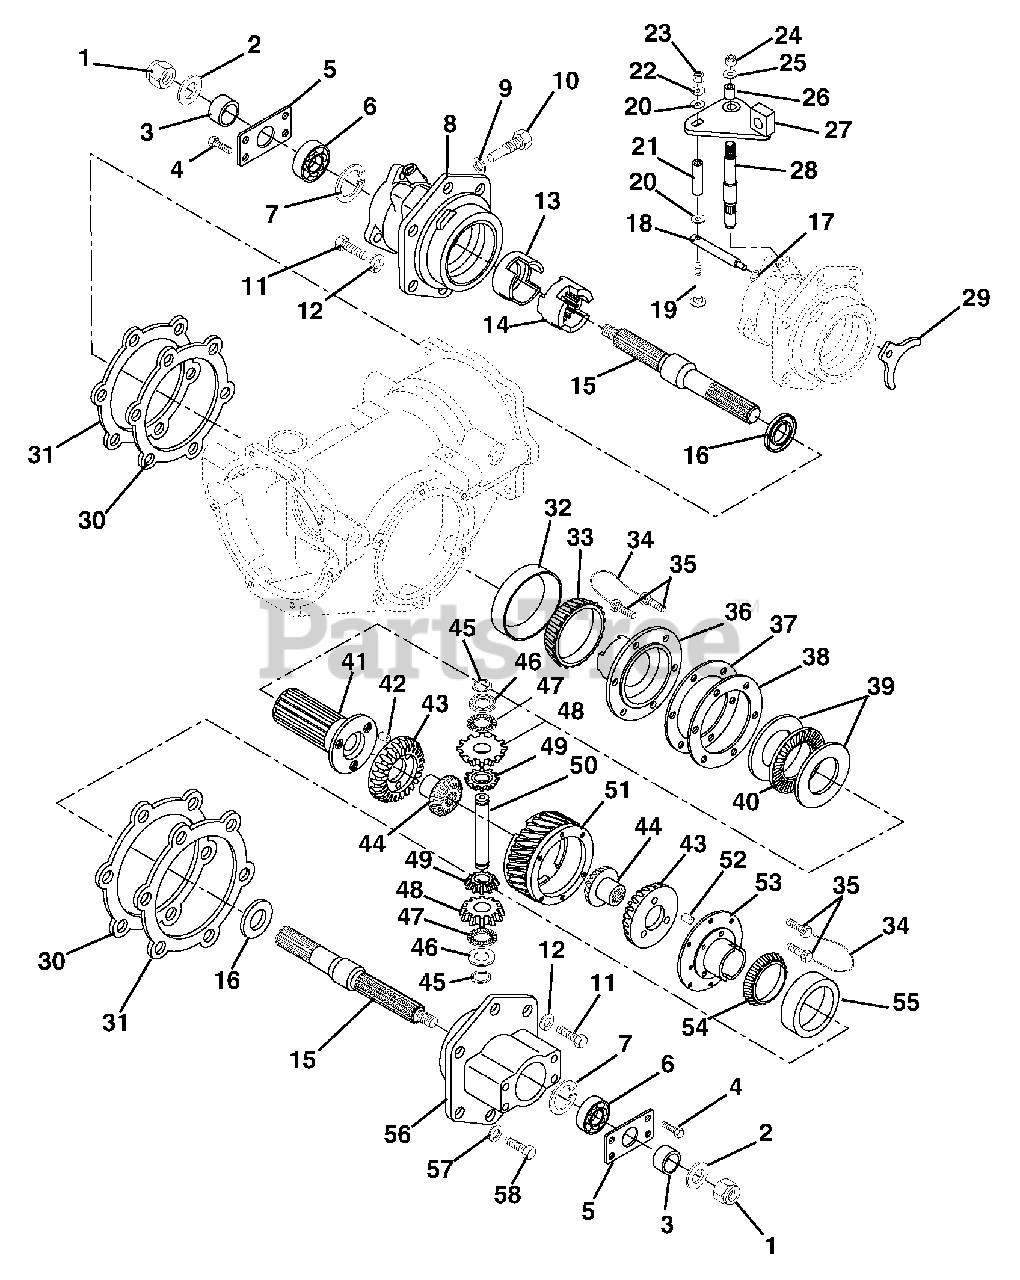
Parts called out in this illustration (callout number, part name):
1	Nut-Locking-Jam-Nylon .75-10
2	Washer-Flat .812 x 1.50 x .135
3	Spacer 1.008 x 1.377 x .509
4	Bolt-Hex .38-16 x .75 Grade 5
5	Plate, End
6	Bearing-Ball 1.0 x 2.0 x .56
7	Ring-Retaining-Internal 2.210 x .062
8	Housing, Axle, 2 Speed
9	Washer-Nut .63 x .875 x .062
10	Bolt-Hex .62-18 x .493 x 1.25
11	Bolt-Hex .50-13 x 1 Grade 5
12	Washer-Lock .50 x .125
13	Clutch, Stationary
14	Clutch, Shifting
15	Axle, Straight
16	Seal 1.1988 x 2.00 x .250
17	O-Ring .437 x .625 x .093
18	Pin-Clutch Sliding
19	Bolt-Round Head Square Neck .25-20 x 2.25 Grade 8
20	Washer-Flat-Steel .406 x .812 x .065
21	Bushing-Sleeve .277 x .375 x 1.37
22	Washer-Flat-Steel .281 x .625 x .065
23	Nut-Locking-Center .250-20 Grade 2
24	Nut-Locking-Center .312-18 Grade 2
25	Washer-Flat-Steel .344 x .688 x .065
26	Bushing-Sleeve .377 x .503 x .88
27	Weldment, Arm Shifter
28	Pivot, Stationary
29	Yoke, Shifting
30	Gasket, Axle Housing
31	Assembly, Advance Casting
32	Bearing-Race 4.34 x .741
33	Bearing-Cone 2.69 x .87
34	Wire, Bolt
35	Bolt-Special .31-18 x .75
36	Housing, Clutch
37	Shim, .020 Clutch Worm Gear
38	Shim, .005 Clutch Worm Gear
39	Washer-Thrust 2.002 x 2.740 x .031
40	Bearing-Needle-Thrust 2.0 x 2.74 x .010
41	Shifter, Splined Pinned
42	Pin-Dowel .375 x .375
43	Gear, Pinned Bevel
44	Gear, Differential Bevel
45	Ring-Retaining .697 x .93
46	Bushing, Flange .761 x 1.24 x 1.24
47	Bearing-Needle-Thrust .754 x 1.24 x .078
48	Gear, Differential Shifting Bevel
49	Gear, Spider Bevel
50	Pin, Spider
51	Gear, Worm 8 Start
52	Pin-Dowel .38 x .500
53	Housing, Pinned
54	Cone, Roller Bearing 50mm x 21.5mm
55	Cup, Roller Bearing 82mm x 17mm
56	Housing, Axle
57	Seal-Oil Drain .563 x 1.250 x .091
58	Bolt-Hex .50-13 x 1.25 Grade 5
